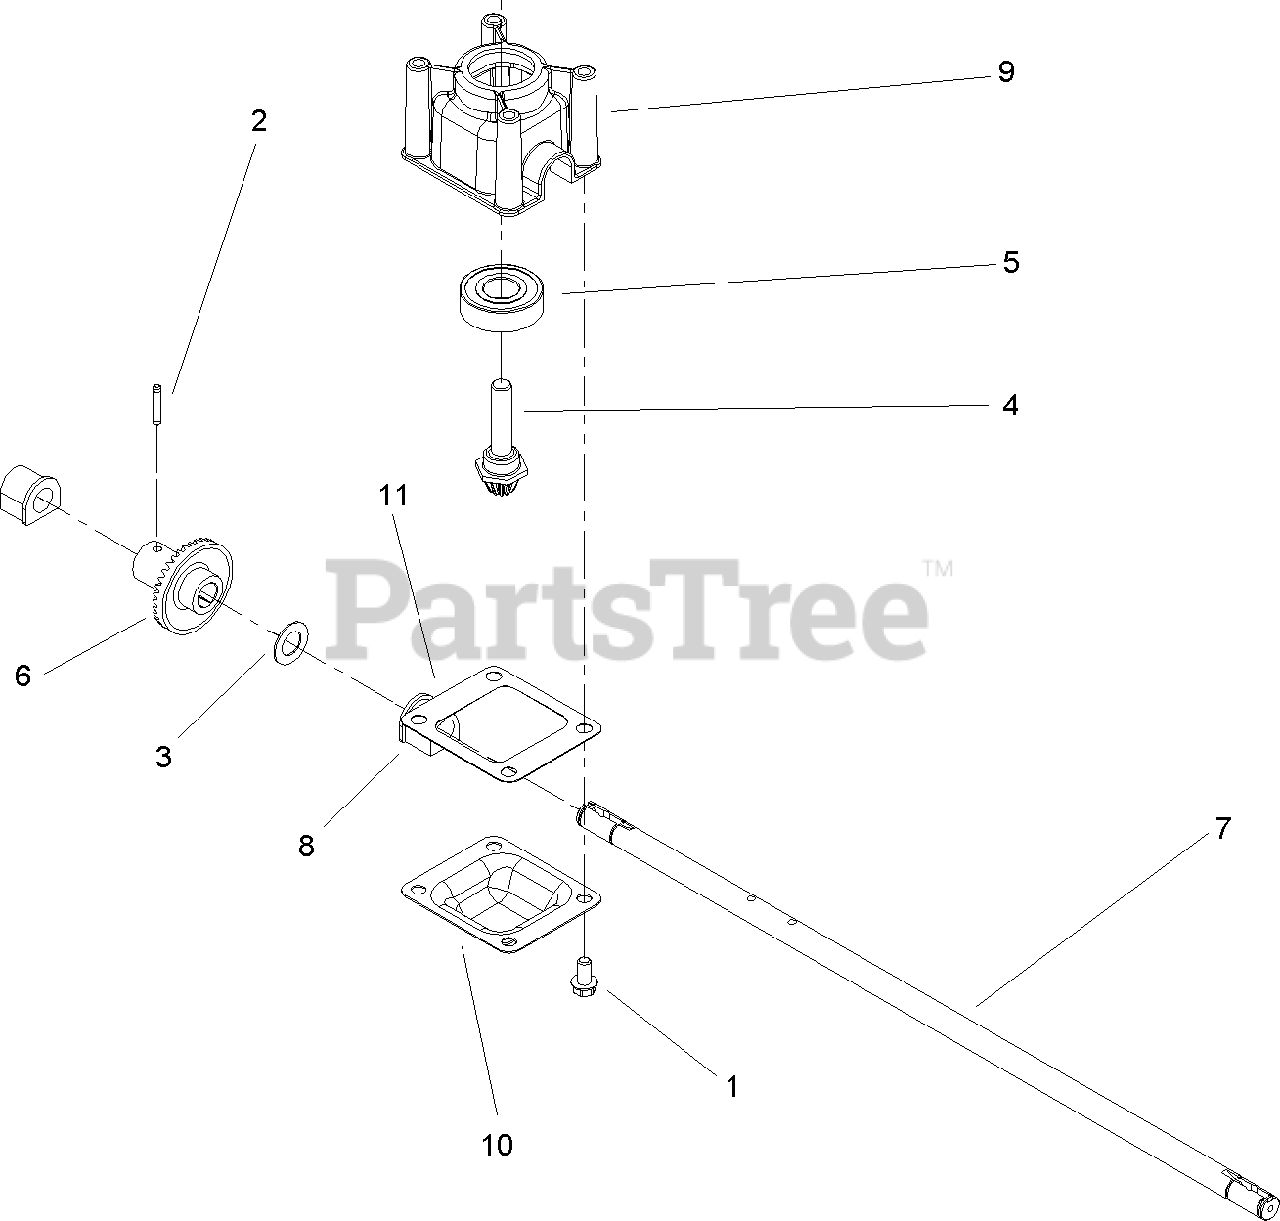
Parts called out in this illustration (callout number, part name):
1	SCREW-HWH
2	PIN-GROOVE
5	BEARING-BALL
6	Gear-Bevel, 37t
7	SHAFT-OUTPUT
8	Bushing-Shaft, Output
9	Gearcase-Upper
10	Cover-Gearcase
11	Gasket-Gearcase
